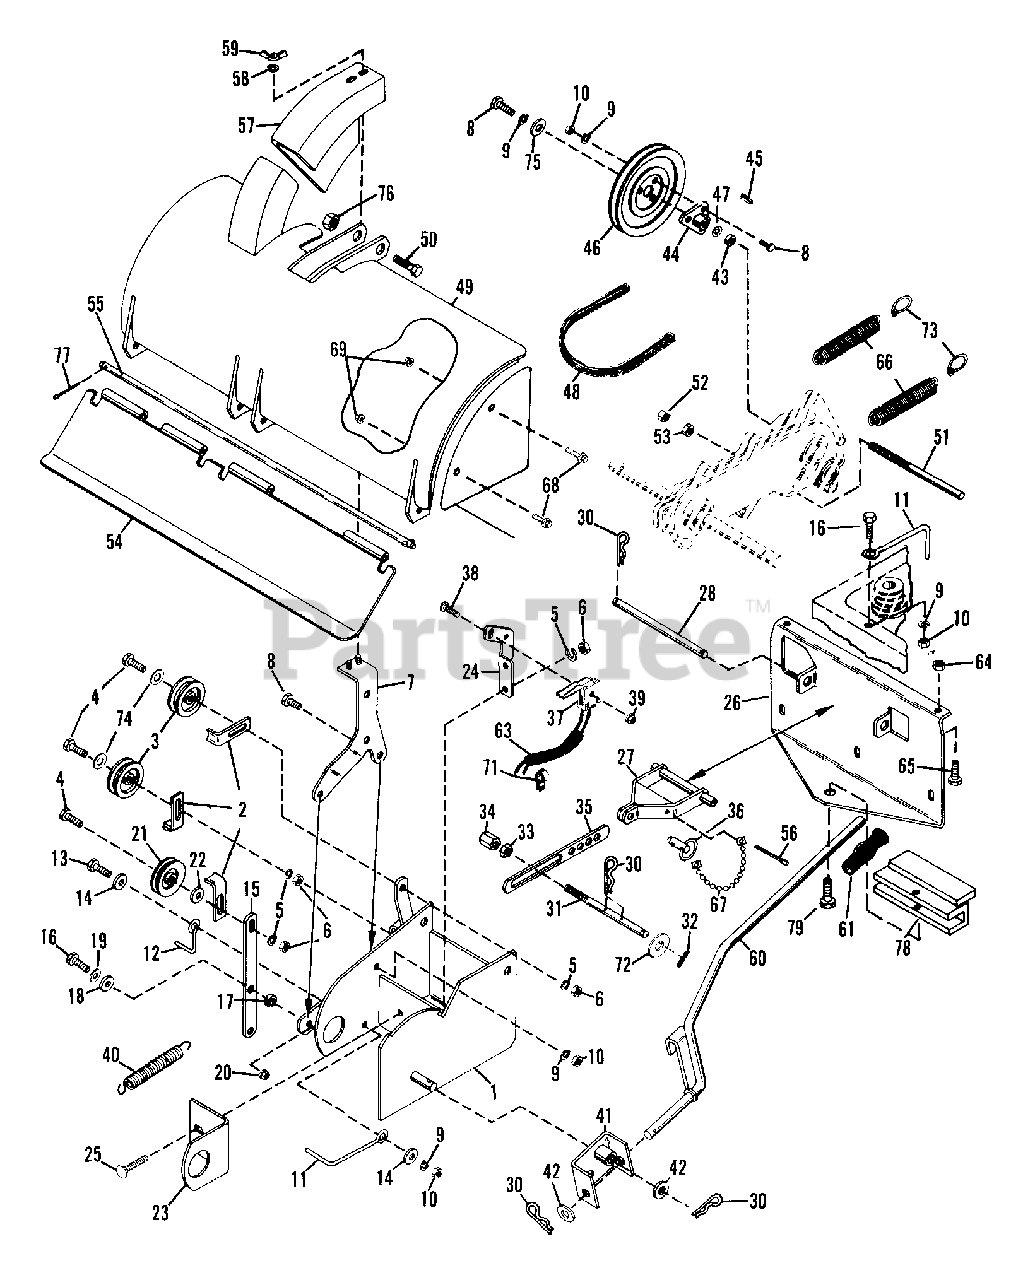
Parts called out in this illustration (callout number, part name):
1	FRAME WELDMENT
2	BELT FINGER
3	IDLER-FLAT 2.75 X .38 DAYCO
4	BLT-HEX .38-16X1.75 PL GR2
5	WSHR-LK .375X.115 HVY PL
6	NUT-HEX .375-16
7	BELT GUARD BRACKET
8	BLT-HEX .31-18X.75 PL GR5
9	WSHR-LK .312X.097 PL HVY
10	NUT-HEX .312-18
11	BELT FINGER
12	BELT FINGER
13	BLT-HEX .31-18X1.25 PL GR5
14	WSHR-FL-STL.344X.688X.065PL
15	CLUTCH ARM
16	BLT-HEX .31-18X1.00 PL GR5
17	SPACER BUSHING .5 X .32 X .21
18	WSHR-FL-STL .505X.875X.024 PL
19	WSHR-FL-STL .323X.625X.062 PL
20	NUT-FLG. .312-18 PL
21	IDLER-V 3.06 X .38
22	WSHR-FL-STL.406X.812X.065PL
23	CHAIN CASE MOUNTING BRACKET
24	SWITCH BRACKET
25	BLT-RDHDSQNK .38-16X1.0 GR5PL
26	TILLER HITCH PLATE
27	DEPTH CONTROL
28	MTG. PIN
30	PIN-HAIR EXT .12X.31X2.37 PL
32	PIN-ROLL .125X1.00
33	NUT-JAM .50-13 PL
34	ADJUSTMENT ROD
35	STEERING COLUMN
36	LATCH PIN
37	SWITCH INTERLOCK
38	SCR-MCH 10-24X1.00 SLRH PL
39	NUT-KEPS 10-24 PL
40	SG-TENS .091X.73X5.28 WLD 30
41	HANDLE PIVOT
42	WSHR-FL-STL .755X1.250X.125
43	SPACER .765X1.000X.781
44	HUB
45	KEY-SQ .188X.625X.188 SAE 61
46	PLY-V 9.0 X 1.25 3BLT
47	WSHR-FL-STL .781X1.000X.015
48	V-BELT, HA-WRAPPED
49	TINE HOOD ASSEMBLY
50	BLT-HEX .31-18X3.00 PL GR5
51	LIFT PIN
52	NUT-LK-CTR .75-10 PL
53	NUT-JAM .75-10 PL
54	TAIL BOARD WELDMENT
55	ROD - TAIL BOARD HINGE
56	PIN-COTR .12X1.0 PL
58	WSHR-LK-EXT. 250 ID
59	NUT-WING .250-20 YWZC
60	LIFT HANDLE WELDMENT
63	WIRE HARNESS
64	NUT-LK-CTR .375-16 GR A PL
65	BLT-HEX .38-16X1.00 PL GR5
66	SG-TENS .162X1.25X8.25 WLD 25
68	BLT-SERHFWH .31-18X.75 PL
69	NUT-FLG. .312-18 PL
70	SIDE PLATE
71	WIRE CLIP
72	WSHR-FL-STL .531X1.062X.095 PL
73	SPRING HOOK
74	WSHR-FL-STL.406X.812X.065PL
75	WSHR-FL-STL .328X1.0X.094
76	NUT-LK .312-18 GR A PL
77	PIN-COTR .09X.75 PL
78	ADAPTOR
79	BLT-HEX .50-13X2.25 PL GR5
